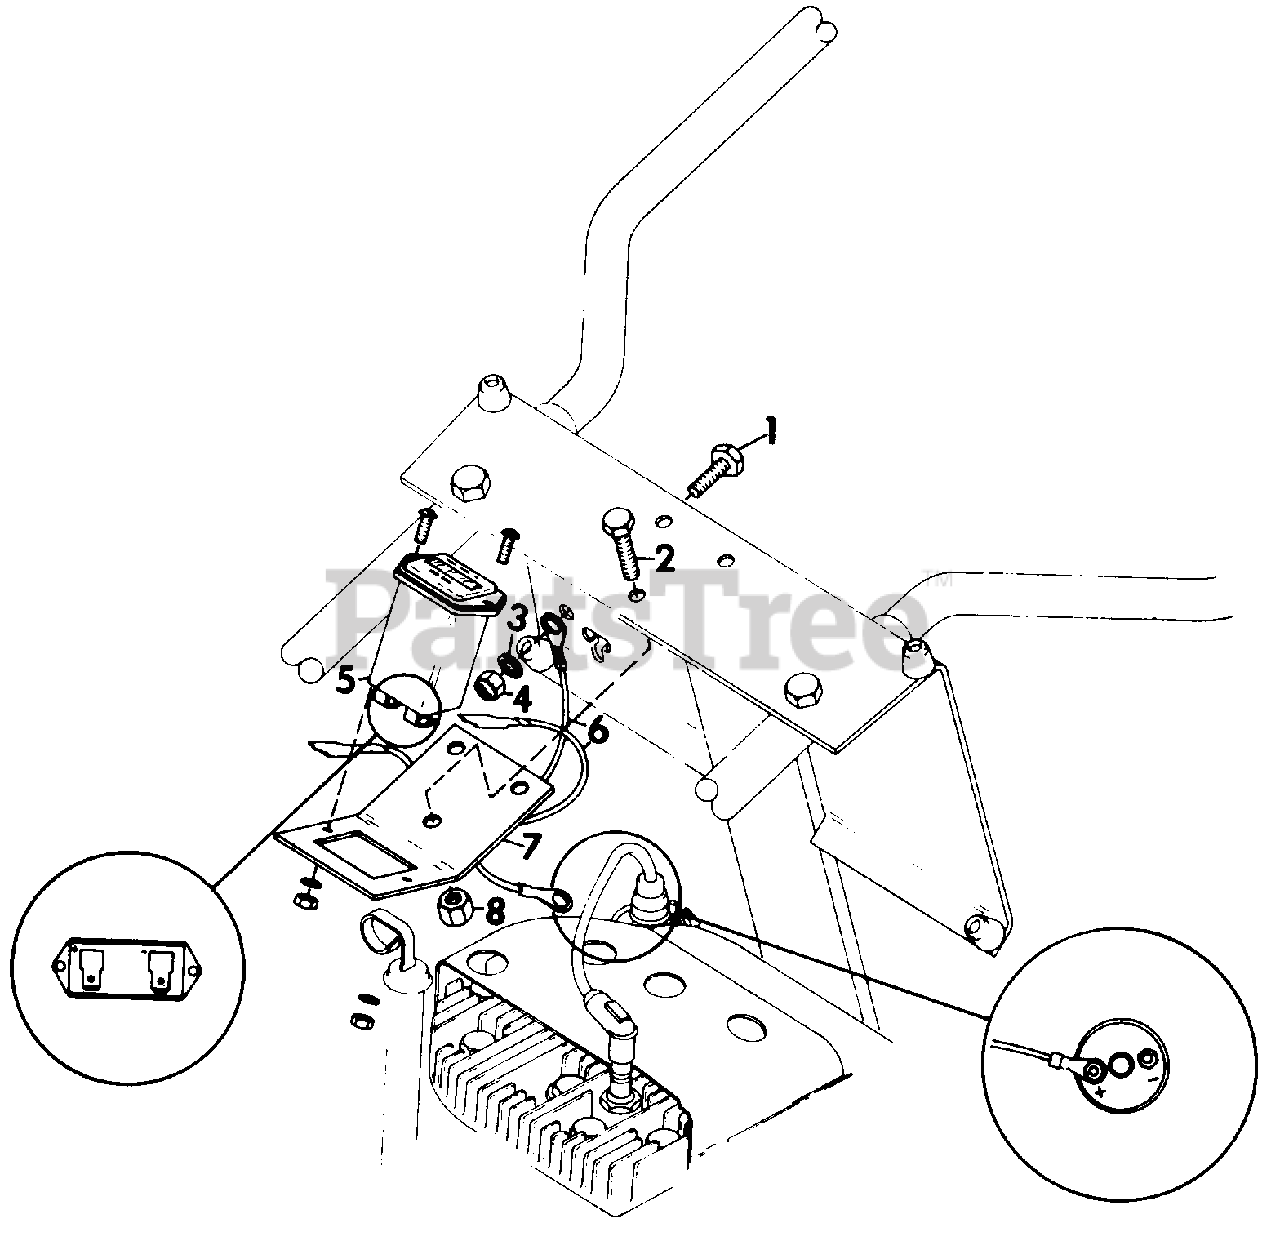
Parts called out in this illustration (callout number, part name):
1	BOLT, HEX 1/4-20X.625
2	BOLT, HEX 3/8-16X.875
3	WASHER, LOCK .25 INT. TOOTH
4	NUT, LOCK 1/4-20
5	HOURMETER
6	WIRE, INSTRUMENT PANEL
7	BRACKET, HOURMETER
8	NUT, LOCK 3/8-16
